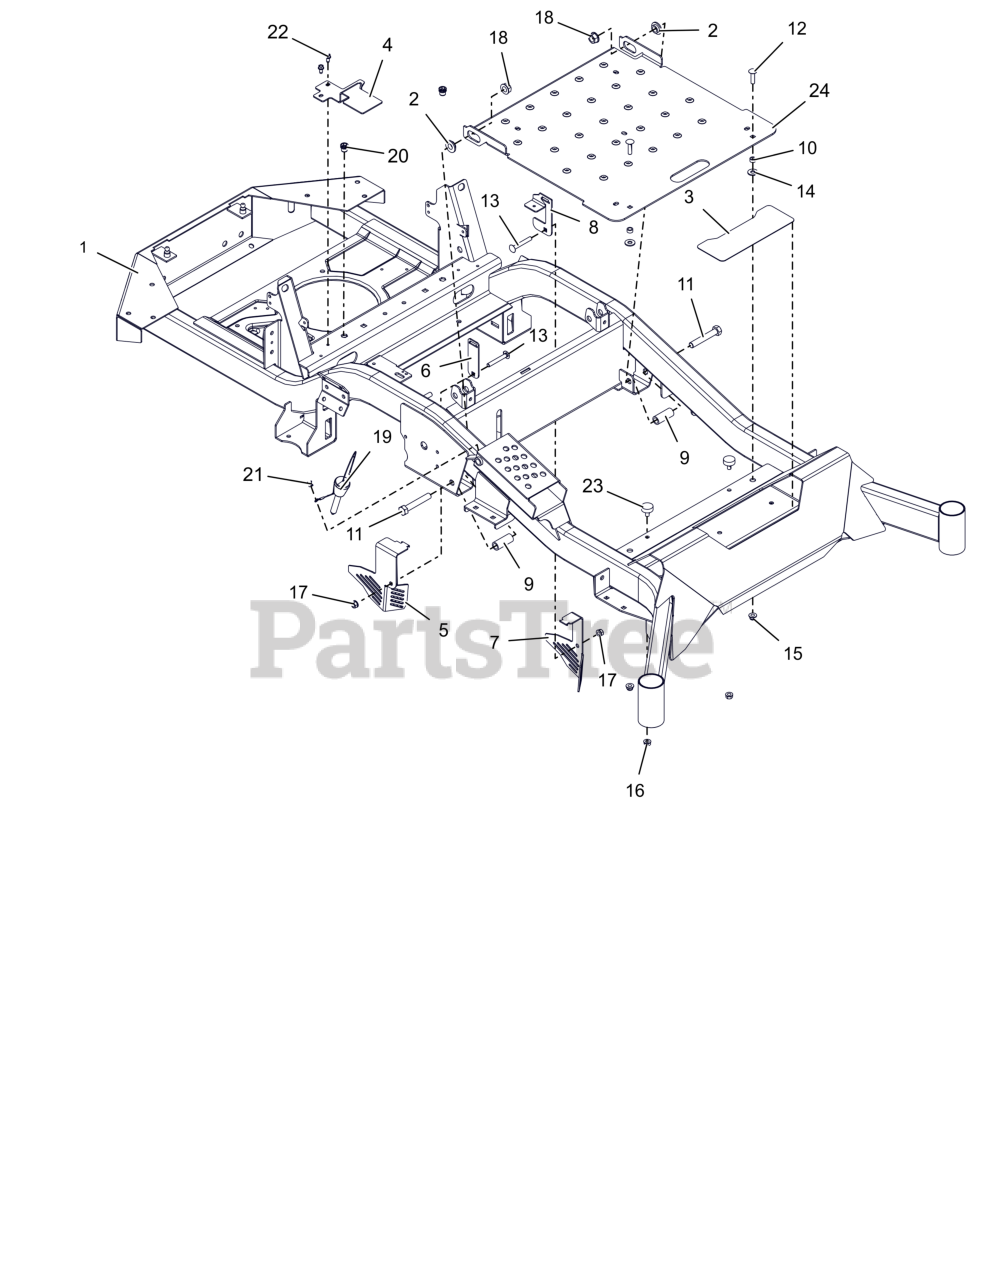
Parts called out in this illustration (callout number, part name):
1	APEX 60"FRAME W/SAFETY DECALS
2	BSHG-FLG .515X.750X.395X1.120
3	GRIP, STEP
4	GUARD, TRANSAXLE FAN RH (BLACK)
5	GUARD, TRANSAXLE FAN - RH
6	BRKT, TRANSAXLE FAN GUARD
7	BRKT, TRANSAXLE FAN GUARD-LH
8	MOUNT, TRANSAXLE GUARD
9	SPACER, .515X.75X1.83
10	BSHG-SLV .344 X .500 X .260
11	BLT, HEX .50-13X3.00 G5 ZCC
12	BLT, RHSSN.31-18X1.25 G5 ZCC
13	BLT, RHSSN.31-18X2.25 G5 ZCC
14	WSHR,FLT .375X.875X.083 ZCC
15	NUT,LK-NYL-FLG .31-18 G5ZC120
16	NUT,SPNLK-FLG .31-18 G5 ZCC
17	NUT,LK-CTR-FLG .31-18 GF ZCC
18	NUT-LK-TOP-FLG .500-13 GF ZCC
19	PIN- MAGNETIC .50X2.70
20	NUT,THD,INSERT .38-16 ZC120
21	POST, & SCREW, PUSH LOCK .25 X .25
22	SCR-TAP .25-20X.50 HWH ZCC
23	BUMPER, RUBBER
24	PANEL, ACCESS
